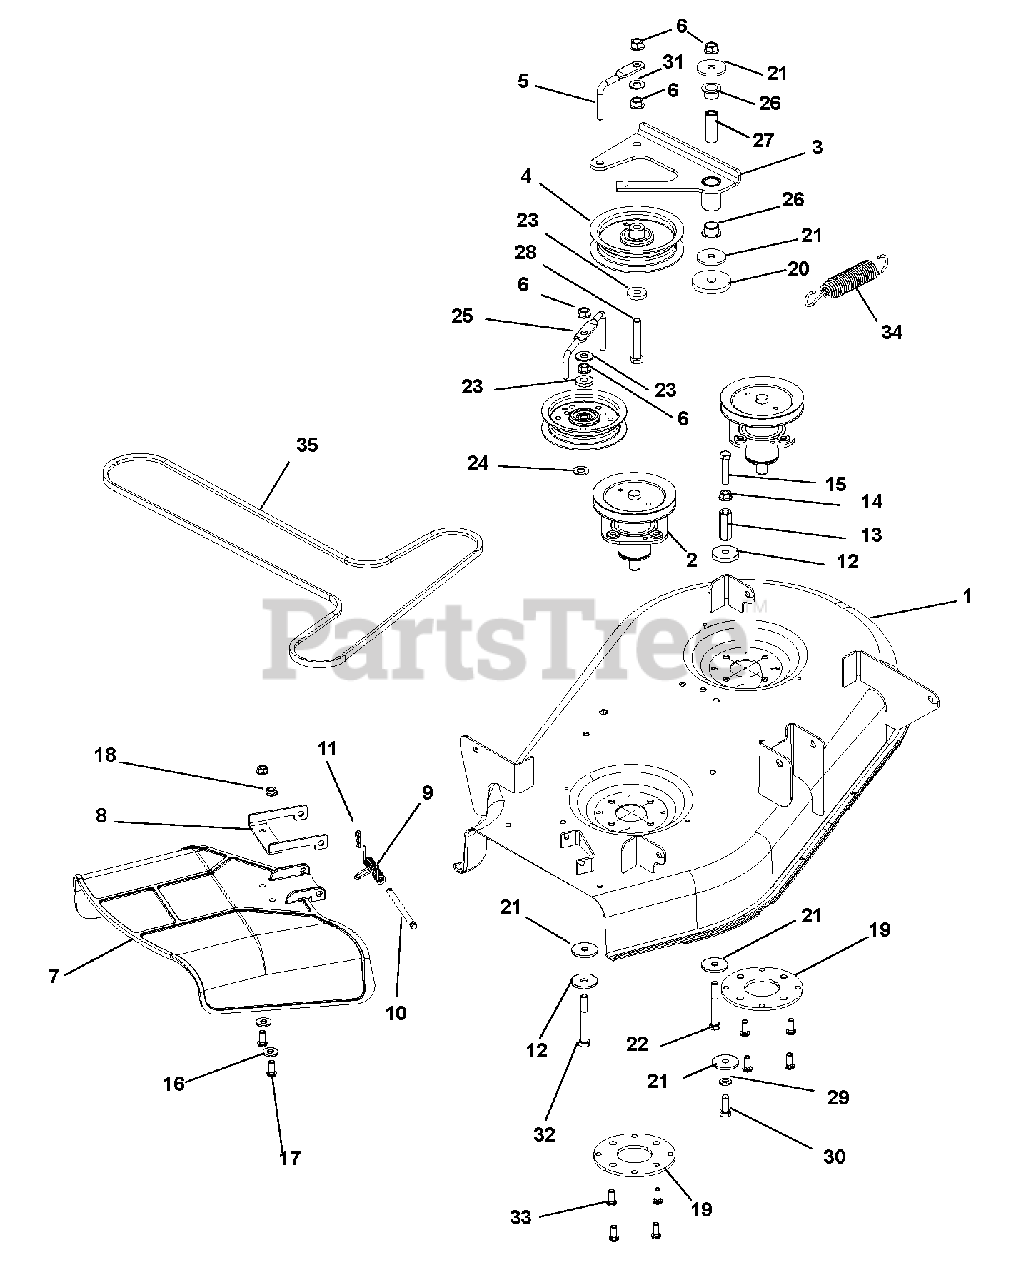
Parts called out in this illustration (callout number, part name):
1	Weldment, Deck 34" CE
2	Assembly, Spindle
3	Weldment, Idler Arm
4	Assembly, Idler 4"
5	Wireform, Belt Finger
6	Nut, Locking Top Flange .38-16
7	Chute, Side Discharge
8	Chute Reinforcement
9	Spring, Torsion
10	Pin, 5/16 x 3.88"
11	Pin, Hair Internal .08 x .18 x 1.18
12	Washer, Flat Steel .406 x 1.50 x .245
13	Nut, Coupling .375-16 x 1.75
14	Nut, Spin Lock, Flange .375-16
15	Bolt, Hex .38-16 x 1.75
16	Washer, Flat Steel .38 x .875 x .083
17	Screw, Socket Head .31-18 x .75 Button Head
18	Nut, Locking Top Flange .31-18
19	Plate, REINF, Spindle
20	Washer, Flat Steel .469 x 2.00 x .25
21	Washer, Flat Steel .380 x 1.50 x .125
22	Bolt, Hex .38-16 x 3.00
23	Washer, Flat Steel .406 x 1.00 x .188
24	Washer, Flat Steel .438 x 1.00 x .083
25	Belt Finger
26	Bushing, Flange, .625 x .750 x .500 x 1.00
27	Spacer, .375ID x .625D x 1.66 Promaster
28	Bolt, Hex .38-16 x 2.25
29	Washer, Locking .38 x .094 Regular
30	Bolt, Hex .38-16 x 1.00
31	Washer, Flat Steel .406 x .812 x .065
32	Bolt, Hex .38-16 x 2.75
33	Screw, Tapping .38-16 x .75 Hex Washer Head Thread Rolling
34	Spring, Tension .135 x .98 x 6.0
35	V-Belt, HA-Wrapped Clutching
